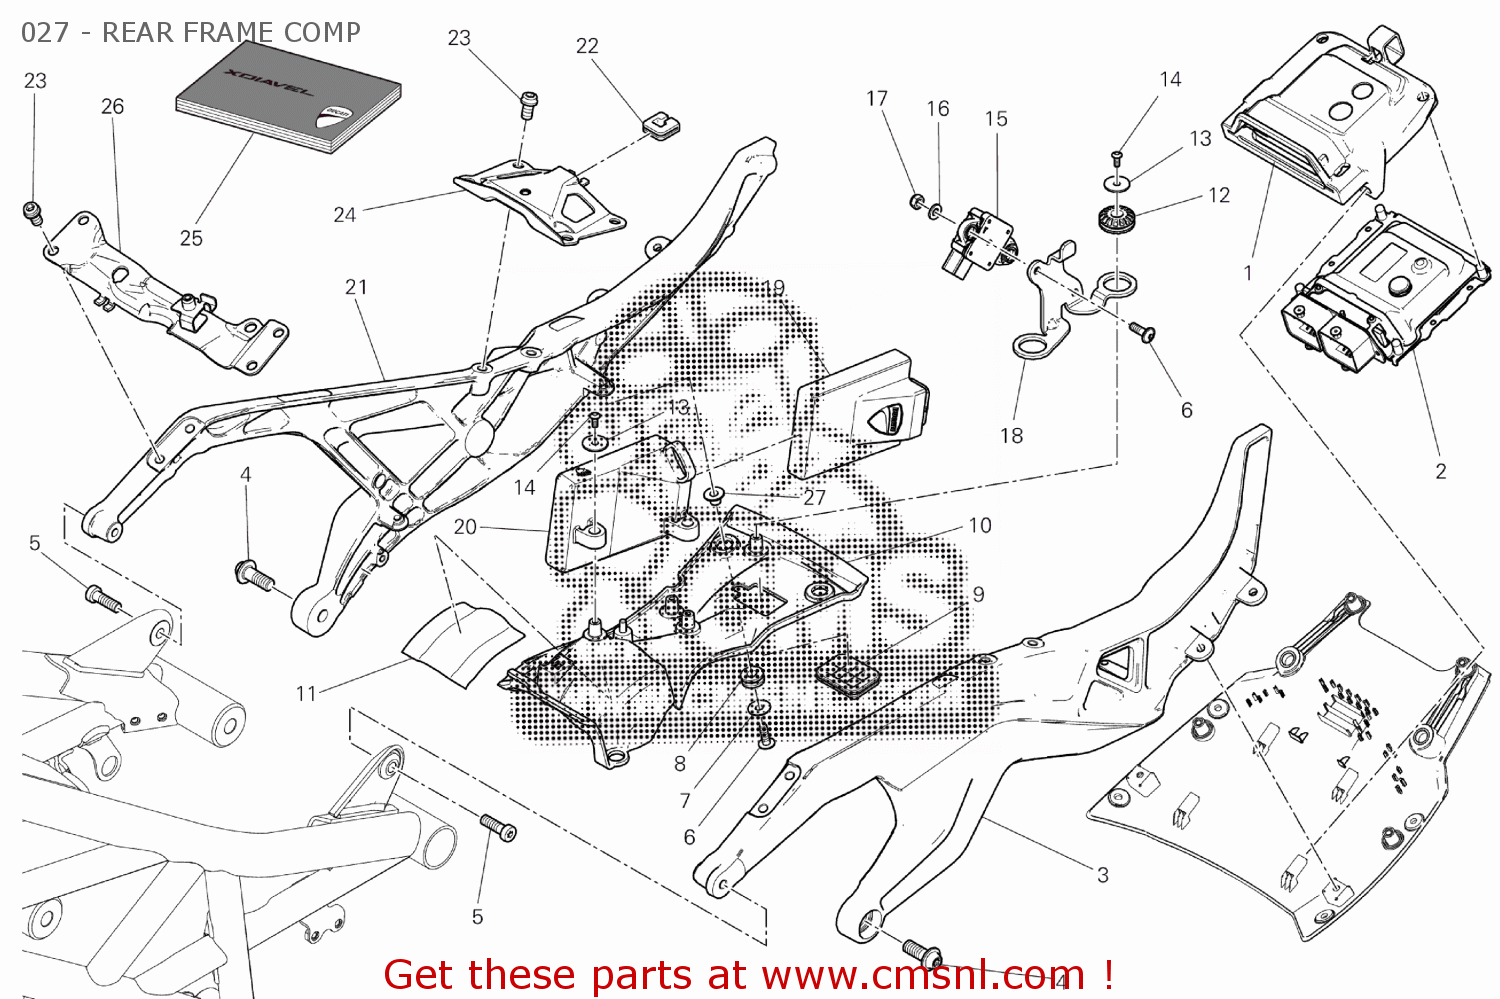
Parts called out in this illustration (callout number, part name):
1	MOUNT RUBBER
2	ENGINE CONTROL UNIT
3	REAR FRAME L.H.
4	SCREW, SPECIAL
5	SCREW
6	SCREW TBEIF M6X18
7	WASHER 6.4X18X1
8	RUBBER PAD
9	PLUG
10	COVER
11	THERMOREFLECTING PROTECTION
12	VIBRATION DAMPER PAD
13	WASHER
14	SCREW, TAPPING
15	PIATTAFORMA INERZIALE
16	WASHER 6.4X12.5X1.6
17	NUT
18	BRACKET
20	MOUNT RUBBER
21	REAR FRAME R.H.
22	RUBBER PAD
23	SCREW TCEIF M8X14 8.8
24	PLATE, REAR FRAME
25	OWNERS MANUAL
26	BRACKET FRONT
27	SPACER
